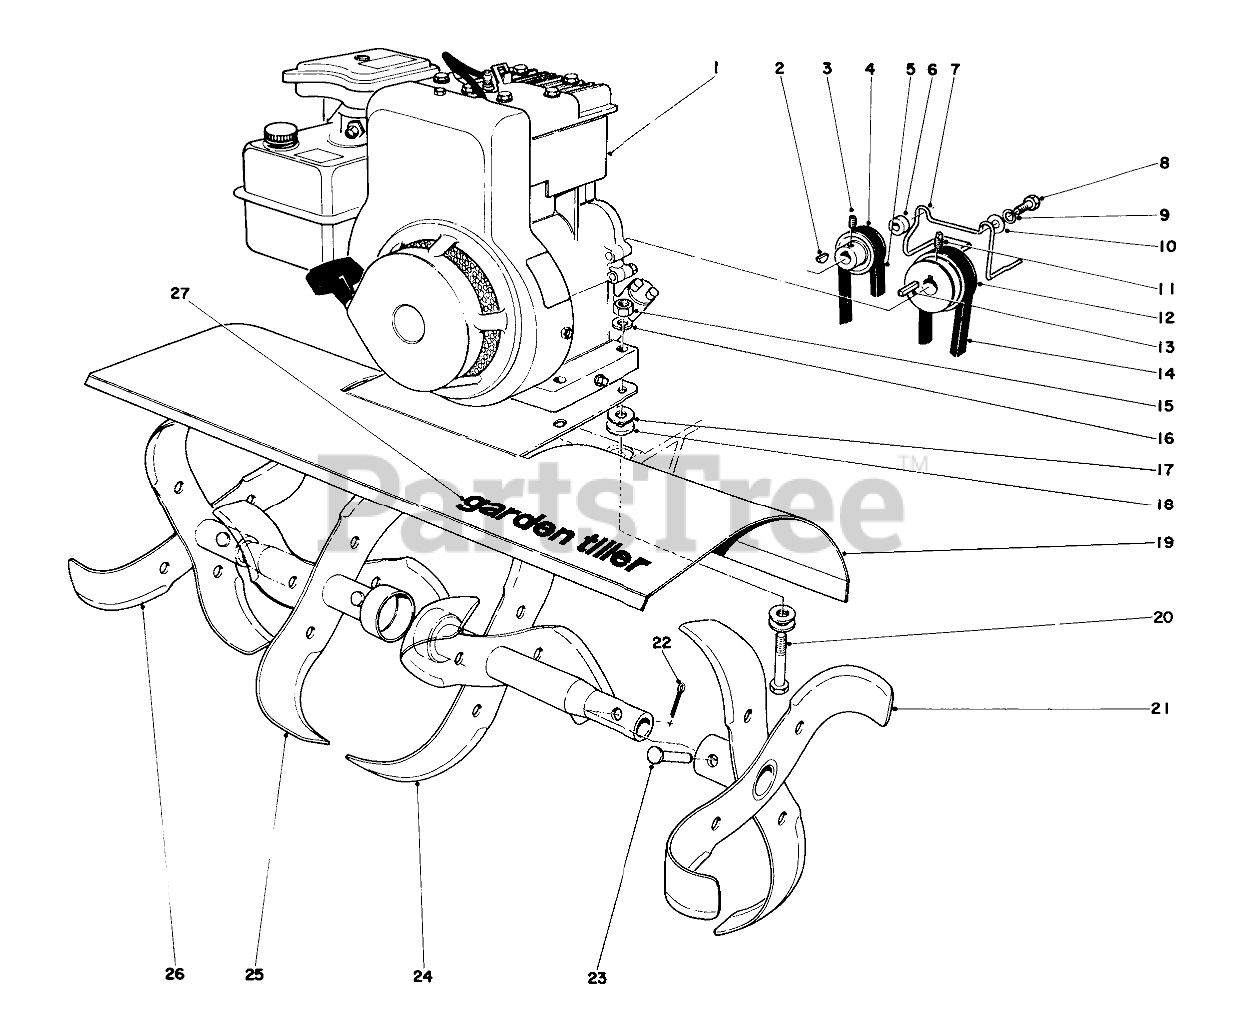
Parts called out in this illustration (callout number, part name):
1	Engine
2	KEY-WOODRUFF
3	SCREW-SET
4	PULLEY
5	V-BELT
6	SPACER
7	BELT GUIDE
8	SCREW-HH
9	WASHER-LOCK
10	WASHER-FLAT
11	SCREW-SET, HSH
12	Engine Pulley
13	KEY-SQUARE
14	Belt
15	NUT-HEX
16	WASHER-LOCK
17	WASHER-FLAT
18	WASHER-FLAT
19	Shield
20	SCREW-HH
21	LH OUT SLASH TINE WA
22	PIN-COTTER
23	TINE PIN
24	Inner Tine L.H.
25	Inner Tine R.H.
26	RH OUT SLASH TINE EA
27	Decal
